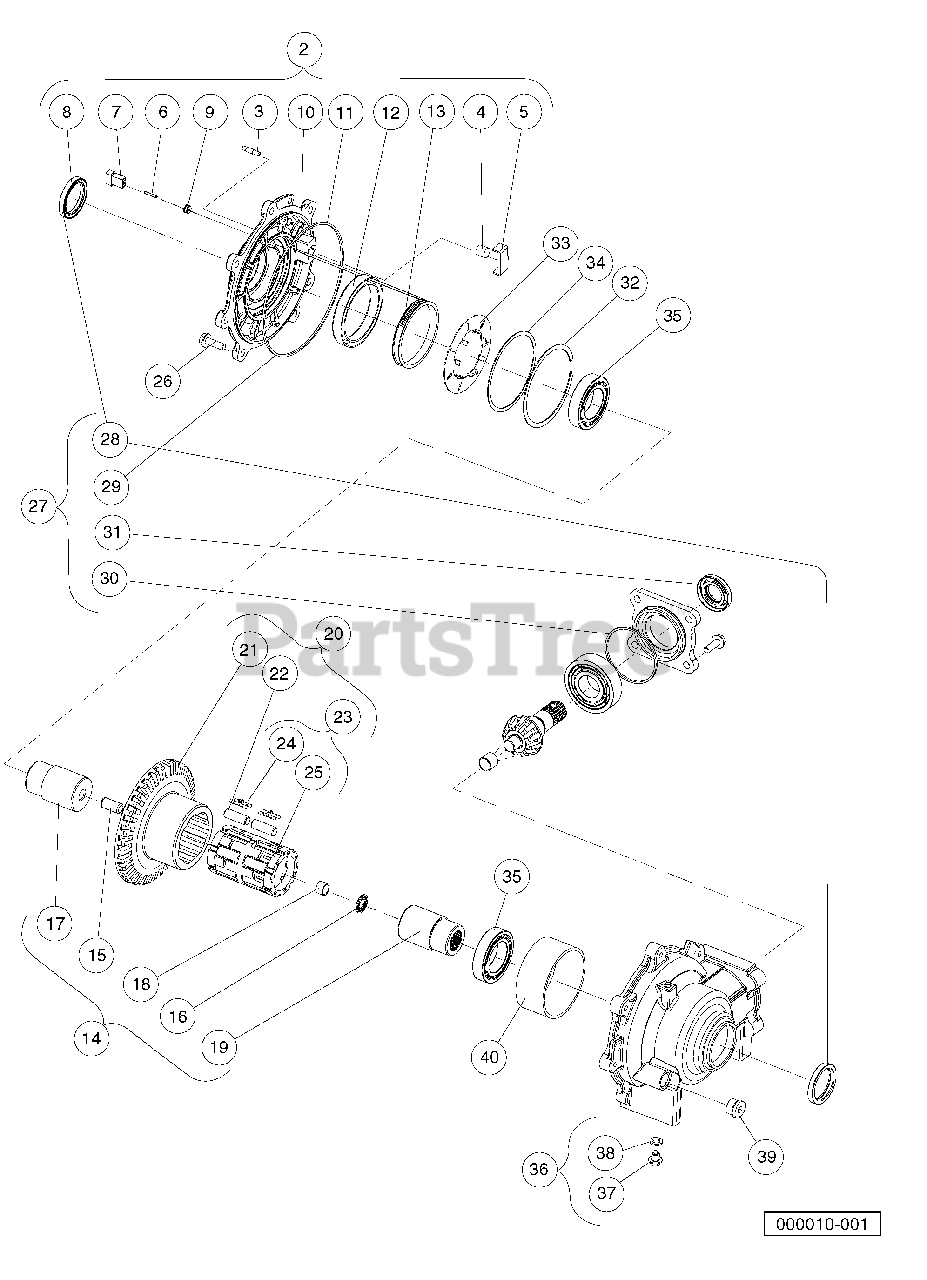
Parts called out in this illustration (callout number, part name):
1	Differential, Front
2	Kit, Assy, Output Cover Plate
3	Set Screw, #10-24 UNC-3A with Patch
4	Thrust Button
5	Thrust Plate
6	Mate-N-Lock Pin
7	Mate-N-Lock Housing
8	Oil Seal
9	Grommet
10	Plate, Output Cover
11	O-Ring
12	Coil, Pocket Insert
13	Coil with Press-Fit Bobbin
14	Kit, Assy, Race Output Hub
15	Pin, Dowel
16	Bearing, Needle
17	Race/Output Hub, Male
18	Bushing, PermiGlide
19	Race/Output Hub, Female
20	Kit, Assy, Clutch
21	Clutch Hsg/Ring Gear, Machined
22	Kit, Roller (contains 14 rollers)
23	Kit, Assy, Roll Cage
24	Kit, H-Clip Spring (contains 14 clips)
25	Roll Cage, Plastic
26	Kit, Bolt (contains 7 bolts)
27	Kit, Minor Repair
28	Oil Seal
29	O-Ring
30	O-Ring
31	Oil Seal, Triple-Lipped
32	Retaining, Ring Internal
33	Plate, Armature
34	Shim, Armature, Plate
35	Bearing, Ball
36	Kit, Assy, Drain Plug
37	Plug, Oil Drain
38	Washer, Nylon, 0.625 x 0.382 x 0.06
39	Plug, Oil Fill
40	Bushing, Self-Lubricating, 80 x 85 x 20
